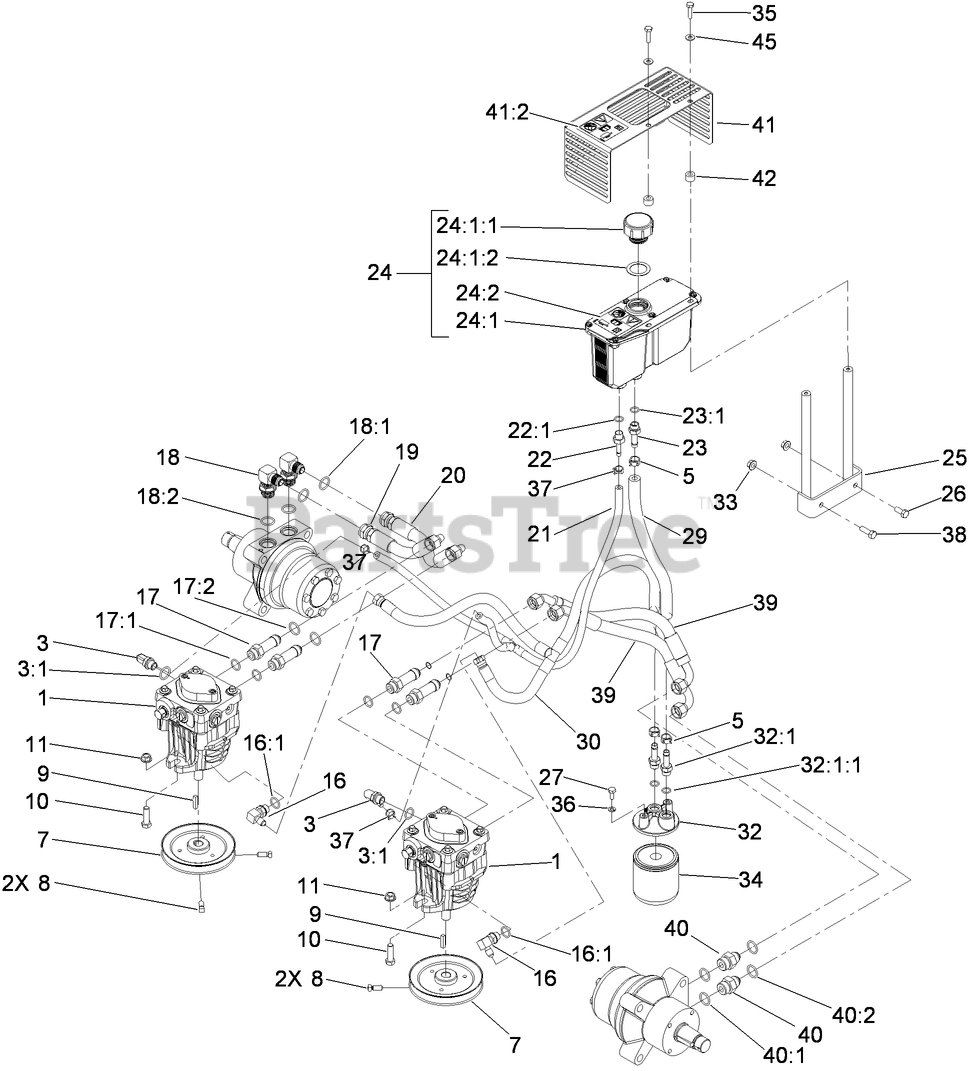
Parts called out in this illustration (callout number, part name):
1	PUMP-HYD
3	ELBOW-90 DEG
3:1	O-RING
5	Clamp-Hose
7	PULLEY
8	SCREW-SET
10	SCREW-HH
11	NUT-HHF, WHIZ
16	FITTING-ELBOW, 90 DEG
16:1	O-Ring
17	ADAPTER-HYD, STRAIGHT
17:1	O-RING
17:2	O-Ring
18	FITTING-HYD, 90 DEG
18:1	O-Ring
18:2	O-RING
19	HOSE-FRONT
20	HOSE-REAR
21	HYD HOSE ASM
22	Adapter-Straight
22:1	O-RING
23	ADAPTER-STRAIGHT
23:1	O-RING
24	HYD RESERVOIR ASM
24:1	Reservoir-HYD
24:1:1	CAP-RESERVOIR, HYD
24:1:2	GASKET-CAP
24:2	DECAL-WARNING
25	STAND-RESERVOIR
26	SCREW-HH
27	SCREW-HH
29	HYD HOSE ASM
30	HYD HOSE ASM
32	Filter Head ASM
32:1	ADAPTER-STRAIGHT
32:1:1	O-RING
33	NUT-HF
34	FILTER-OIL, HYD
34	FILTER-OIL, HYD (WINTER)
35	SCREW-HH
36	WASHER-LOCK
37	Clamp-Hose
38	SCREW-HH
39	HOSE ASM
40	Fitting-Straight
40:1	O-RING
40:2	O-Ring
41	SHIELD ASM
41:2	DECAL-WARNING
42	Spacer
45	WASHER-FLAT
